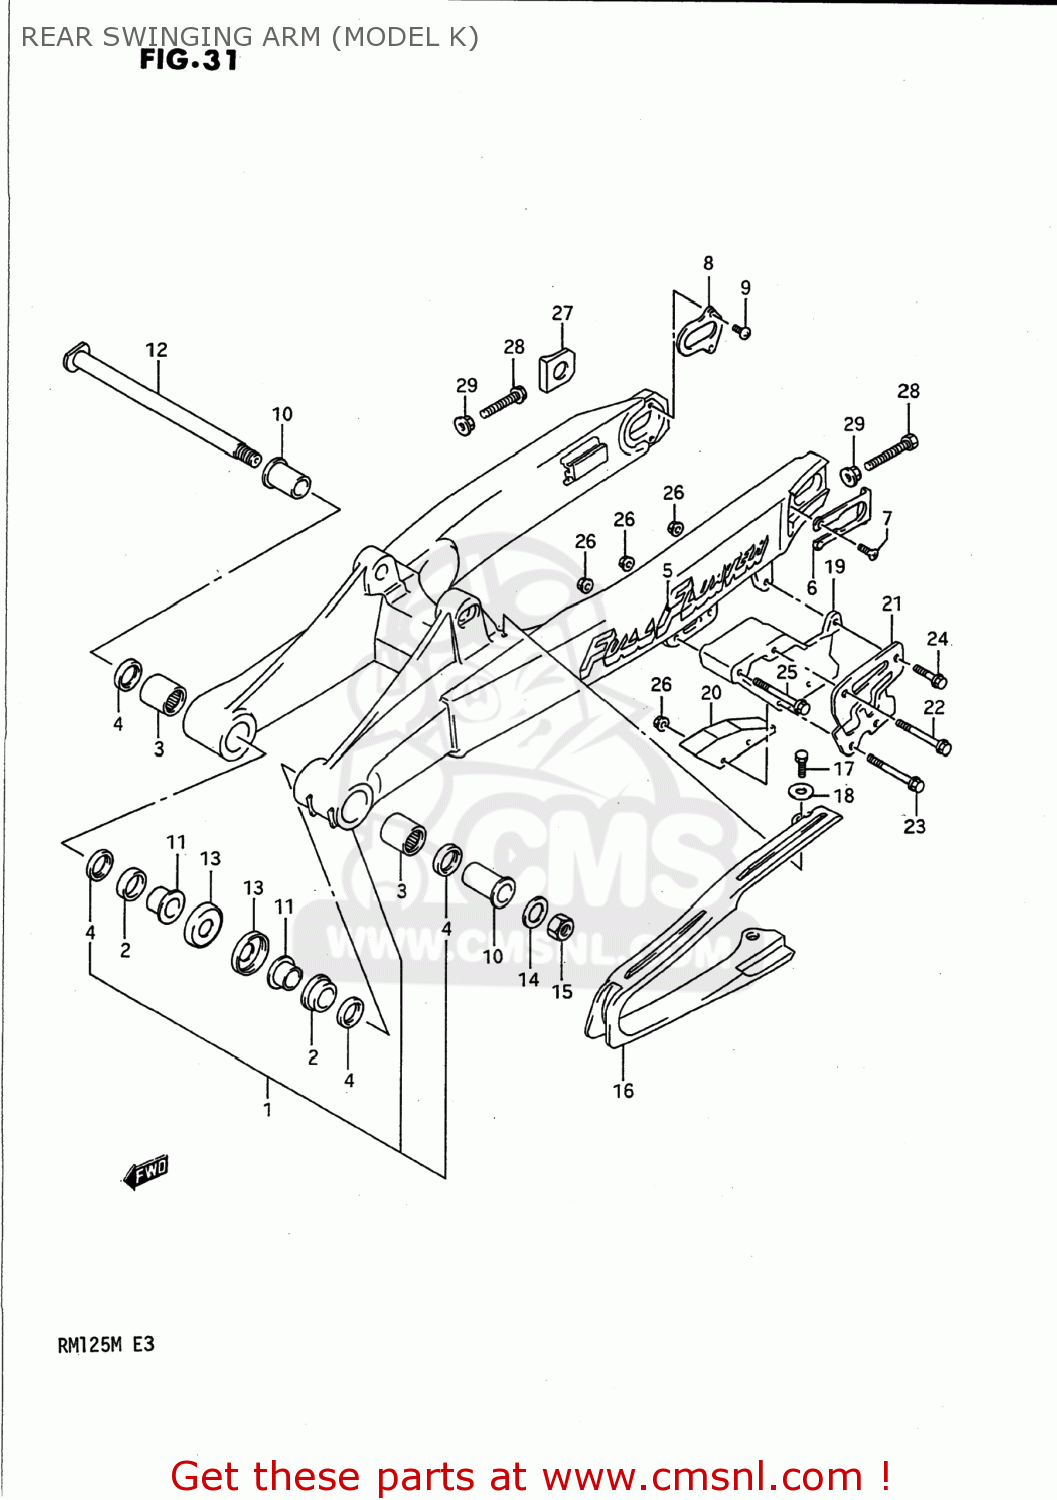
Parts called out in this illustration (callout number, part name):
1	SWING ARM ASSEMBLY,REAR
2	BUSHING,SWGARM PIVOT
3	BEARING(20X27X30)
4	OIL SEAL
5	LABEL (FRONT CARRIER WARNING)
6	PLATE,OUTER
7	SCREW(5X10)
8	PLATE,REAR SWING ARM
9	SCREW (5X8)
10	SPACER,RR SWGARM PIVOT
11	SPACER,SWGARM PIVOT INNER
12	SHAFT,RR SWINGINGARM PIVOT
13	COVER,SWING ARM PIVOT
14	WASHER(14.2X24X2.3)
15	NUT
16	BUFFER,CHAIN TOUCH DEFENSE
17	BOLT
18	WASHER
19	GUIDE,CHAIN
20	DEFENSE,CHAIN GUIDE
21	PLATE,CHAIN GUIDE OUTER
22	BOLT
23	BOLT
24	BOLT
25	BOLT
26	NUT
27	WASHER,CHAIN ADJUSTER
28	BOLT
29	NUT
